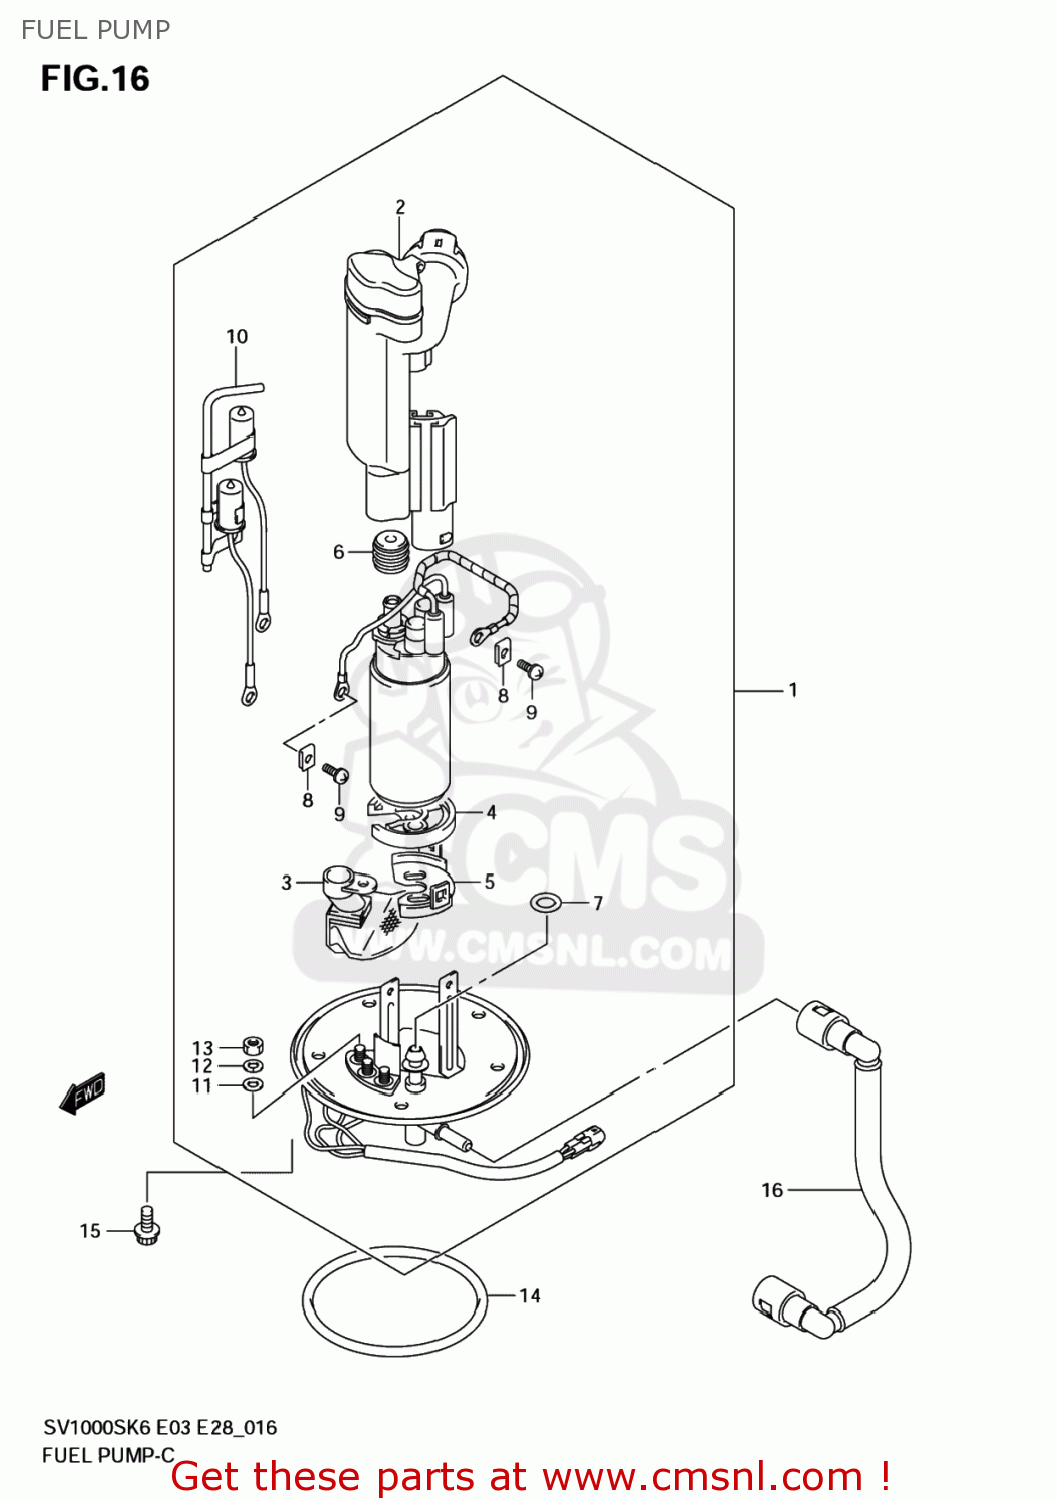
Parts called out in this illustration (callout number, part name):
1	PUMP ASSY,FUEL
2	FILTER,FUEL
3	STRAINER,FUEL PUMP
4	CUSHION
5	HOLDER,FUEL PUMP
6	BUSH,FUEL PUMP
7	O RING
8	NUT
9	SCREW
10	THERMISTOR
11	WASHER
12	WASHER,SPRING
13	NUT
14	O RING,FUEL PUMP
15	BOLT
16	HOSE COMP,FUEL
